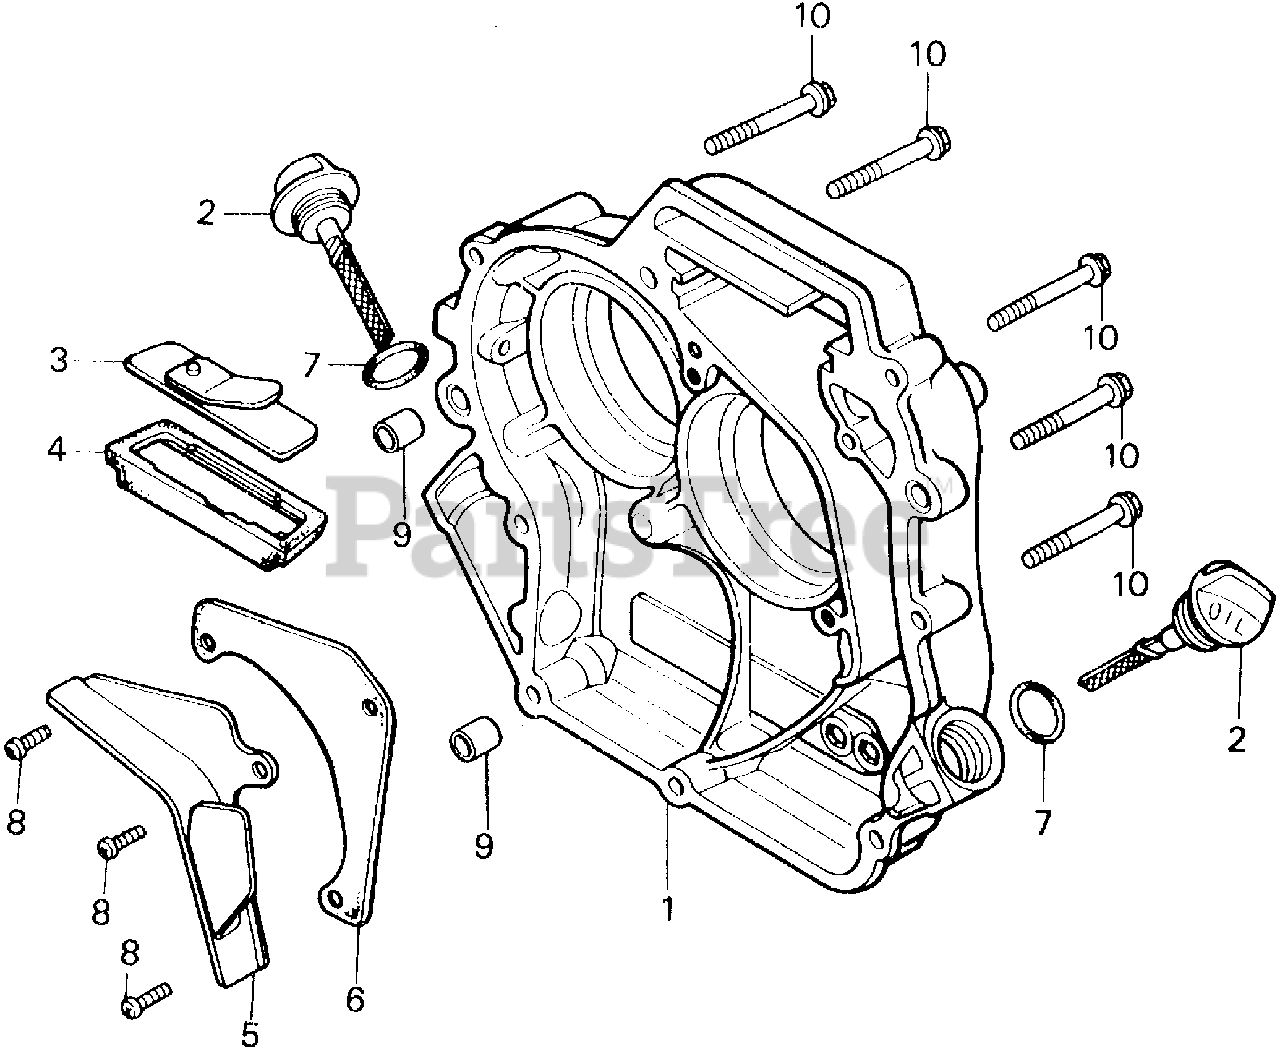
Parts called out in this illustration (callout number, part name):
1	COVER, CRANKCASE
2	CAP, OIL (NOT AVAILABLE)
3	PLATE, BREATHER
4	RUBBER, BREATHER PLATE
5	SEPARATOR, BREATHER
6	GASKET, SEPARATOR
7	O-RING (16MM)
8	SCREW, PAN (5X12)
9	PIN A, DOWEL (8X14)
10	BOLT, FLANGE (6X32)
